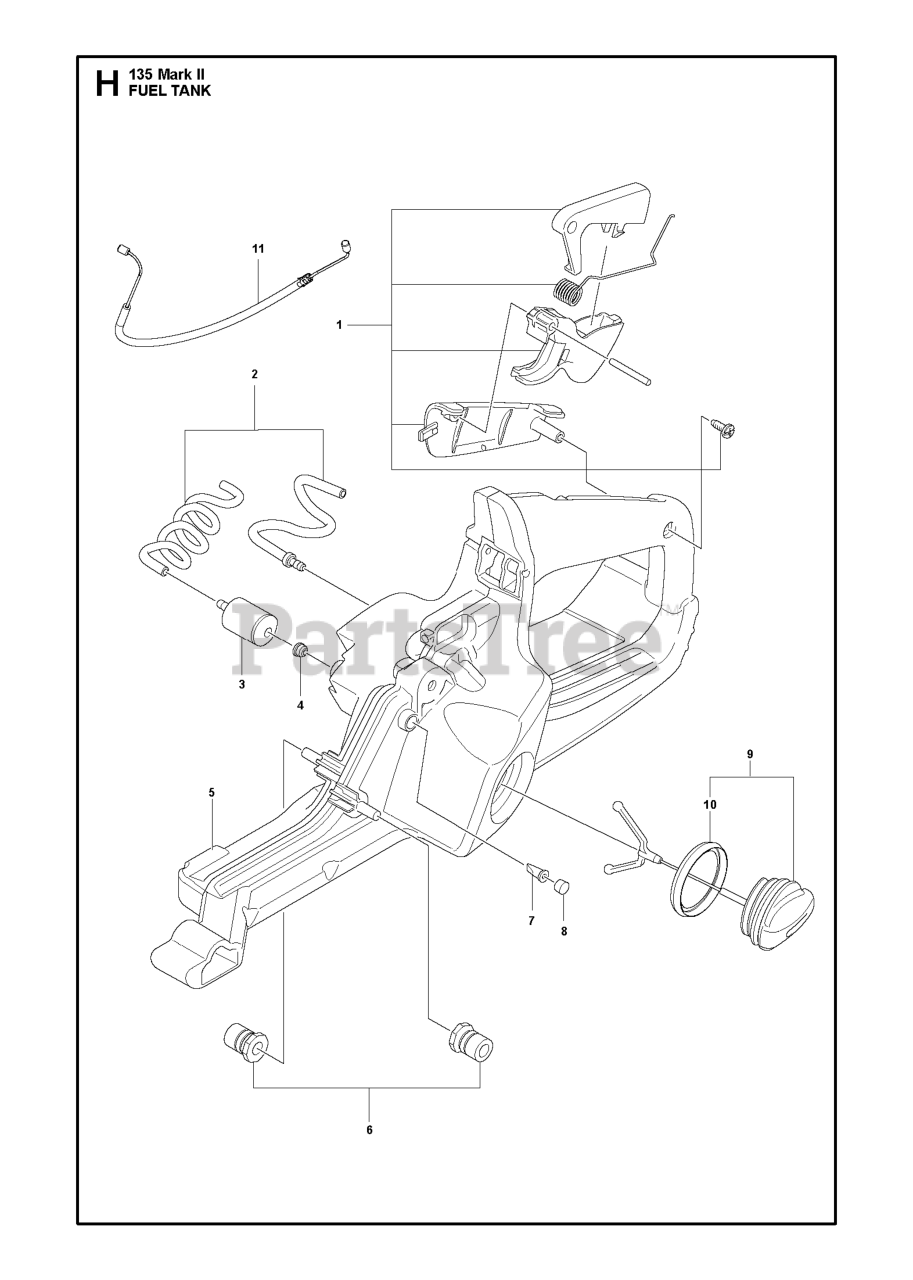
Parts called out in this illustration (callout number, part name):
1	SERVICE KIT TRIGGER ASSEMBLY
2	SERVICE KIT FUEL HOSE ASSEMBLY
3	RP FUEL FILTER
4	FUEL TANK BUSHING
5	FUEL TANK ASSY WELDED 38 CC LO
6	SERVICE KIT LATERAL SUPPORT
7	VALVE-CHECK (DUCKBILL)
8	VENT,FUEL TANK 36/41
9	ASSY TANK CAP GREY
